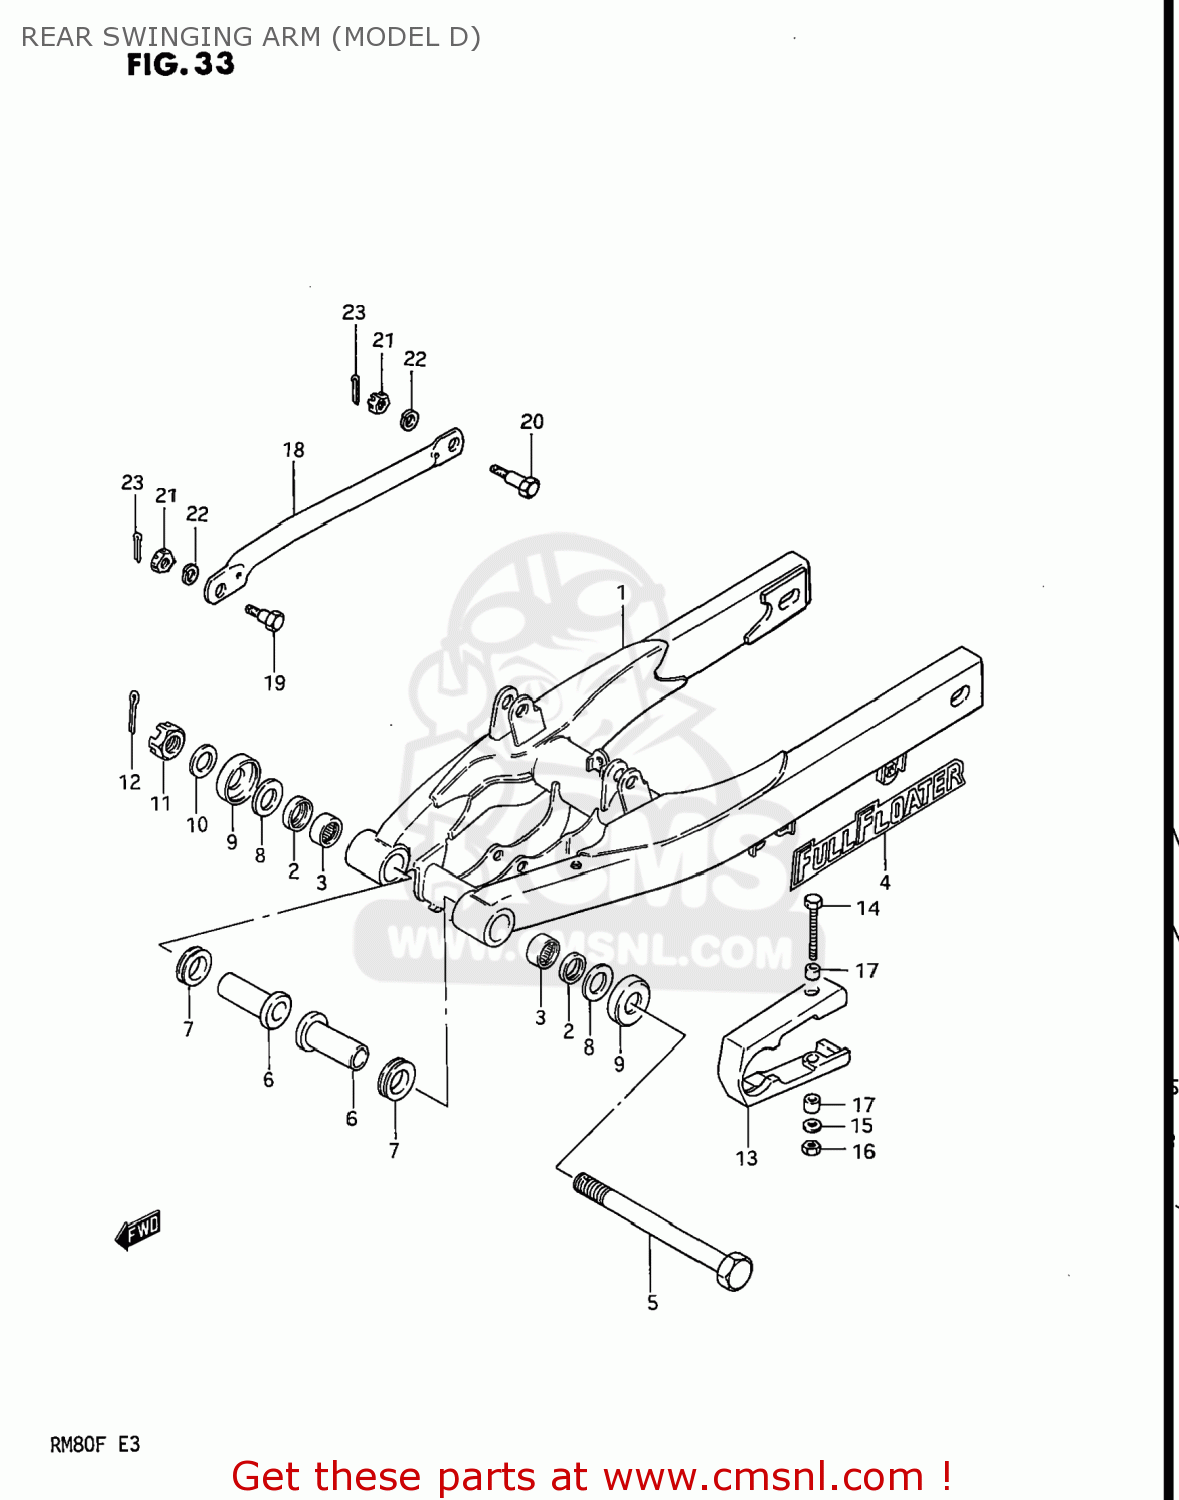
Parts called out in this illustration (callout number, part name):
1	SWING ARM ASSEMBLY,REAR
2	SEAL,OIL(17X24X3)
3	ROLLER BEARING (17X24X2
4	EMBLEM
5	SHAFT,REAR SWING ARM
6	SPACER,RR SWGARM PIVOT
7	SEAL,OIL(17X24X5)
8	WASHER
9	COVER,RR SWGARM DUST SEAL
10	WASHER
11	NUT, REAR AXLE
12	COTTER PIN
13	BUFFER,CHAIN TOUCH DEFLECTOR
14	SCREW,CHAIN TOUCH DEFEND
15	WASHER
16	NUT
17	SPACER (5.5X8X4)
18	LINK,REAR TORQUE
19	BOLT(8X22)
20	BOLT(8X21)
21	NUT
22	LOCK WASHER
23	PIN 20X20
